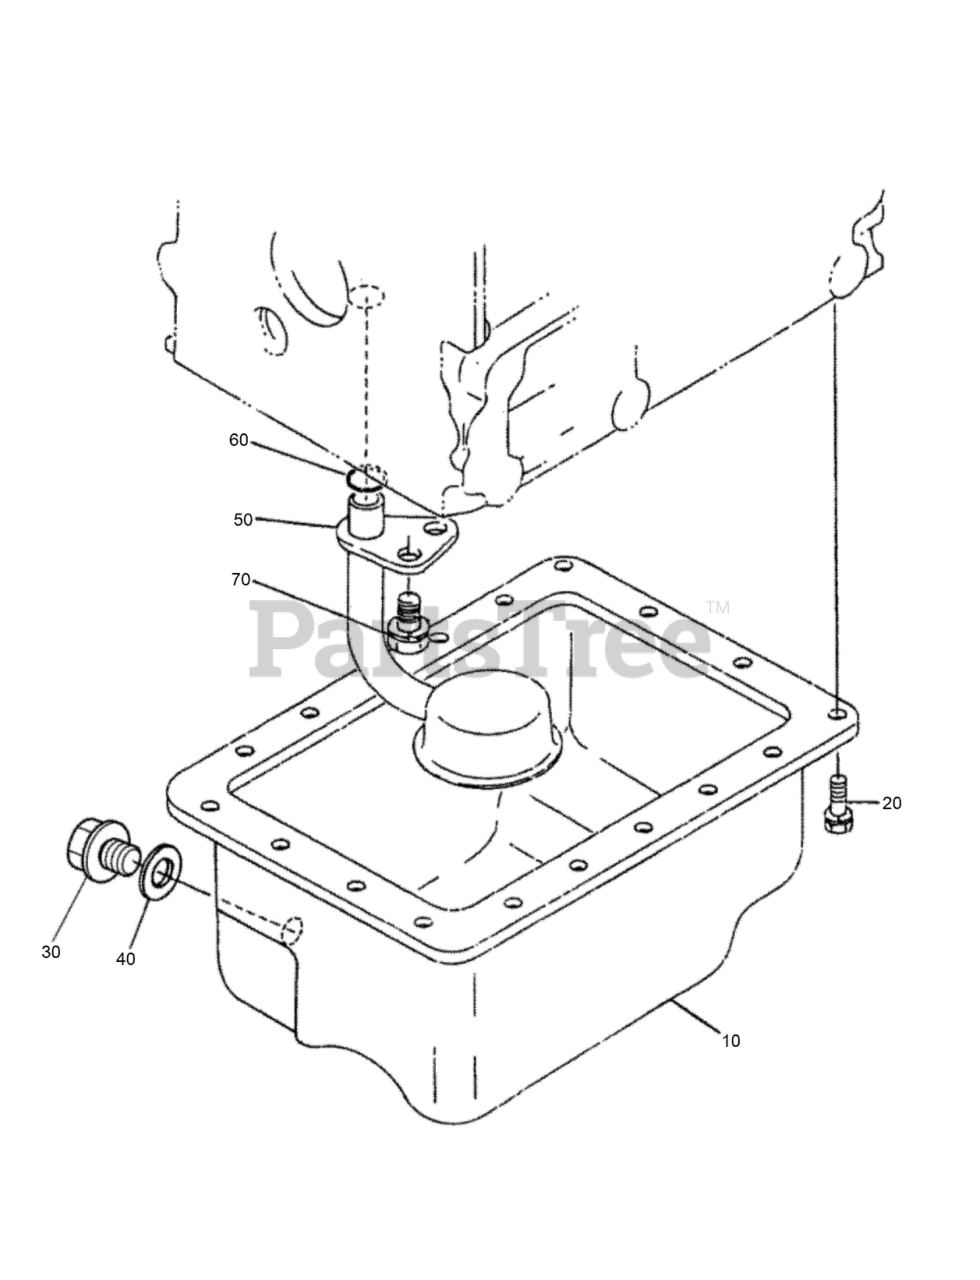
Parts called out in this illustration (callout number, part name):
10	COMP.OIL PAN
30	PLUG-DRAIN
40	GASKET
50	STRAINER-PICKUP, OIL
60	O-RING
